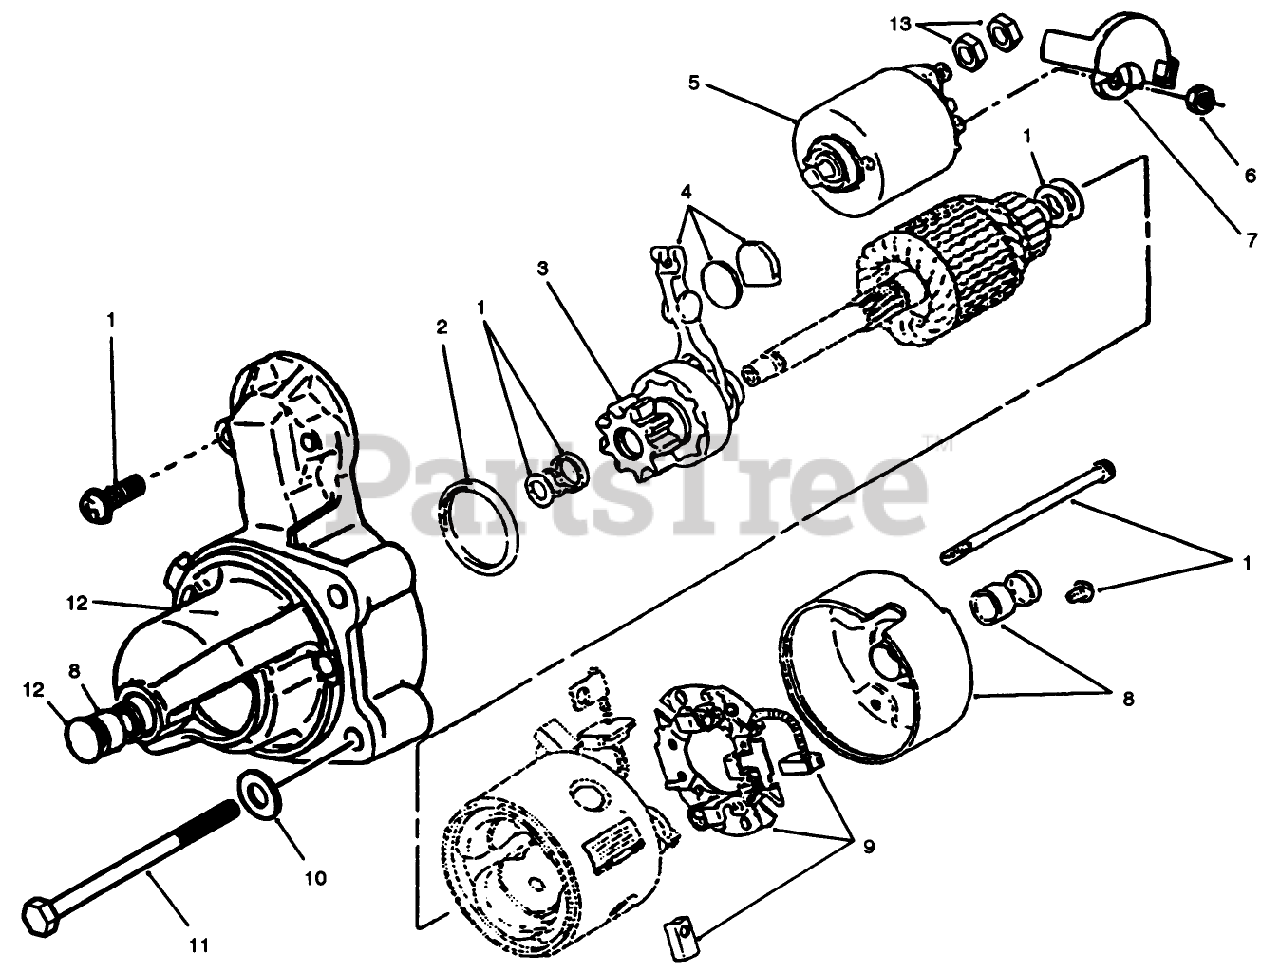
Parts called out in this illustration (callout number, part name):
2	Dust Seal
3	CLUTCH STARTER ASSEMBLY
4	LEVER
5	STARTER SOLENOID KIT
6	Nut-Hex.
7	COVER-SOLENOID STARTER
8	BUSHING
9	BRUSH KIT
10	WASHER
11	SCREW-HH
12	Brush Mounting Kit
13	NUT-JAM
